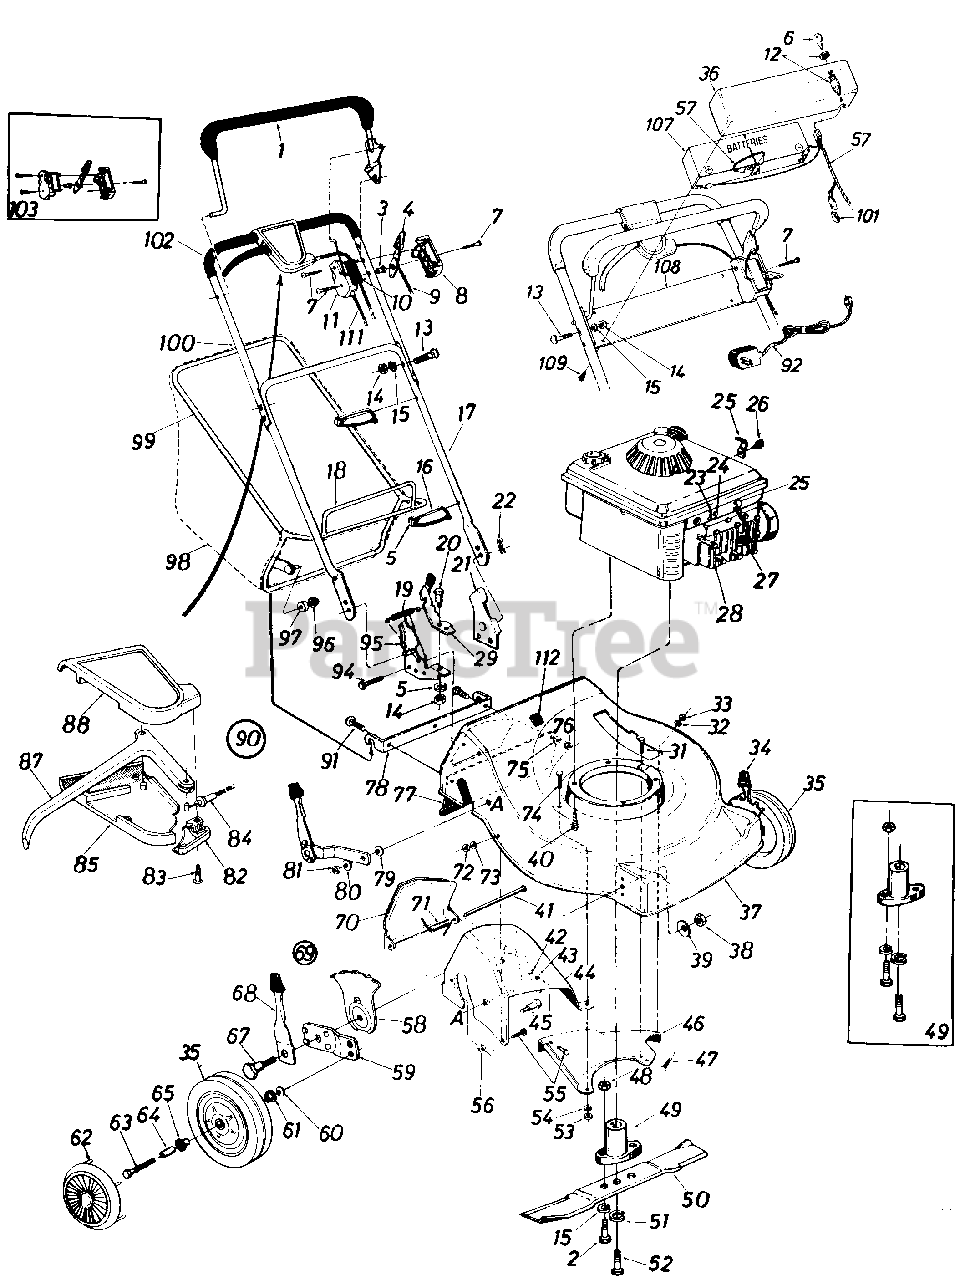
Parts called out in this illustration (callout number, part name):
1	Control Handle
2	Hex Bolt 5/16-24 x 1.00" Lg. (Grade 5)
3	Control Disc Pin
4	Throttle Control Lever
5	Cable Anchor
6	Ignition Key
7	Truss Mach. B-Tap Scr. #12 x 1.50" Lg.
8	Control Panel Half
9	Throttle Control Wire-58"
10	Control Label
11	Clutch Panel Half
12	Ignition Switch
13	Curved Carr. Bolt 5/16-18 x 1.38 " Lg .
14	Hex Nut 5/16-18 Thd.
15	L-Wash. 5/16" I.D.
16	Cable Tie
17	Lower Handle
20	Shld. Bolt .437" Dia. x .162
21	Handle Brkt. Ass'y.-L.H.
22	Hairpin Cotter 5/16" Dia.
23	Casing Clamp
24	Hex B-Tap Scr. #10 x .62" Lg.
25	Cable Clip
26	Hex B-Tap Scr. #10 x .38"
27	Spark Plug Insulator
28	Engine
29	Lock Lever w/Knob
31	Hex TT-Tap Scr. 1/4-20 x .75" Lg.
32	L-Wash. 1/4" I.D.
33	Hex Nut 1/4-20 Thd.
34	Height Adj. Ass'y.-L.H.
35	Front Wheel Ass'y. Comp.
36	Battery Tray
39	Bell-Wash. .39" I.D. x 1.38"
40	Hex Wash. Hd. TT-Tap Scr. 3/8-16 x 1.0" Lg.
41	Hinge Pin
42	Hex Nut 1/4-20 Thd.
43	L-Wash. 1/4" I.D.*
44	Rear Chute-R.H.
45	Shld. Bolt .5" Dia. x .685"
46	Rear Baffle-L.H.
47	Carr. Bolt 1/4-20 x .50" Lg.
48	Hex Nut 5/16-24 Thd.
49	Blade Adapter Kit
50	22" Blade
51	L-Wash. 3/8" I.D. H.D.
52	Hex Bolt 3/8-24 x 2.25" Lg. (Grade 5)
53	Hex Nut 1/4-20 Thd.
54	L-Wash. 1/4" I.D.
55	Carr. Bolt 1/4-20 x .50" Lg.
56	Hex Sems Nut 1/4-20 Thd.
57	Wire Harness
58	Height Adj. Plate
59	Wheel Pivot Bar
60	Bell-Wash. .40" I.D. x .88"
61	Flg. Ball Brg. 3/8" I.D.
62	Plastic Hub Cap
63	Hex Bolt 3/8-16 x 1.75" Lg.
64	Spacer .375" I.D.
65	Flg. Ball Brg. 1/2" I.D.
67	Shld. Bolt .50" Dia. x .430
68	Spring Lever Ass'y. w/Knob
69	Height Adj. Ass'y.-R.H.
70	Chute Door
71	Torsion Spring
72	Hex Nut 1/4-20 Thd.
73	L-Wash. 1/4" I.D.
74	Hex Bolt 1/4-20 x .88" Lg.
75	Fl-Wash. .285" I.D. x 1.25"
76	Hex Sems Nut 1/4-20 Thd.
77	Rear Flap
78	Grass Catcher Hitch Brkt.
79	Bell-Wash. .40" I.D. x 1.13"
80	Bell-Wash. .400" I.D. x .88"
81	Hex Jam Nut 3/8-16 Thd.
82	Cable Mounting Cap
83	Flat "C"Sunk Hd. Tap Scr. #10 x .75" Lg.
84	S.P. Cable-43" Lg.
85	Control-Lower Cover
87	Control Lever
88	Control-Upper Cover
90	Clutch Control Hsg. Comp.
91	Carr. Bolt 1/4-20 x .75" Lg.
92	Battery Charger
94	Hex Wash. Hd. AB-Tap Scr. 1/4" x.62" Lg.
95	Handle Brkt. Ass'y.-R.H.
96	Push Nut 3/8" Rod
97	Plastic Roller
98	Grass Bag
99	Catcher Upper Frame
100	Upper Handle
101	Plug
103	Control Housing Comp.
107	Battery Pack
108	Lower Battery Tray
109	Truss Mach. Hi-Riser Tap Scr. 1" Lg.
111	Clutch Control Cable-45"
